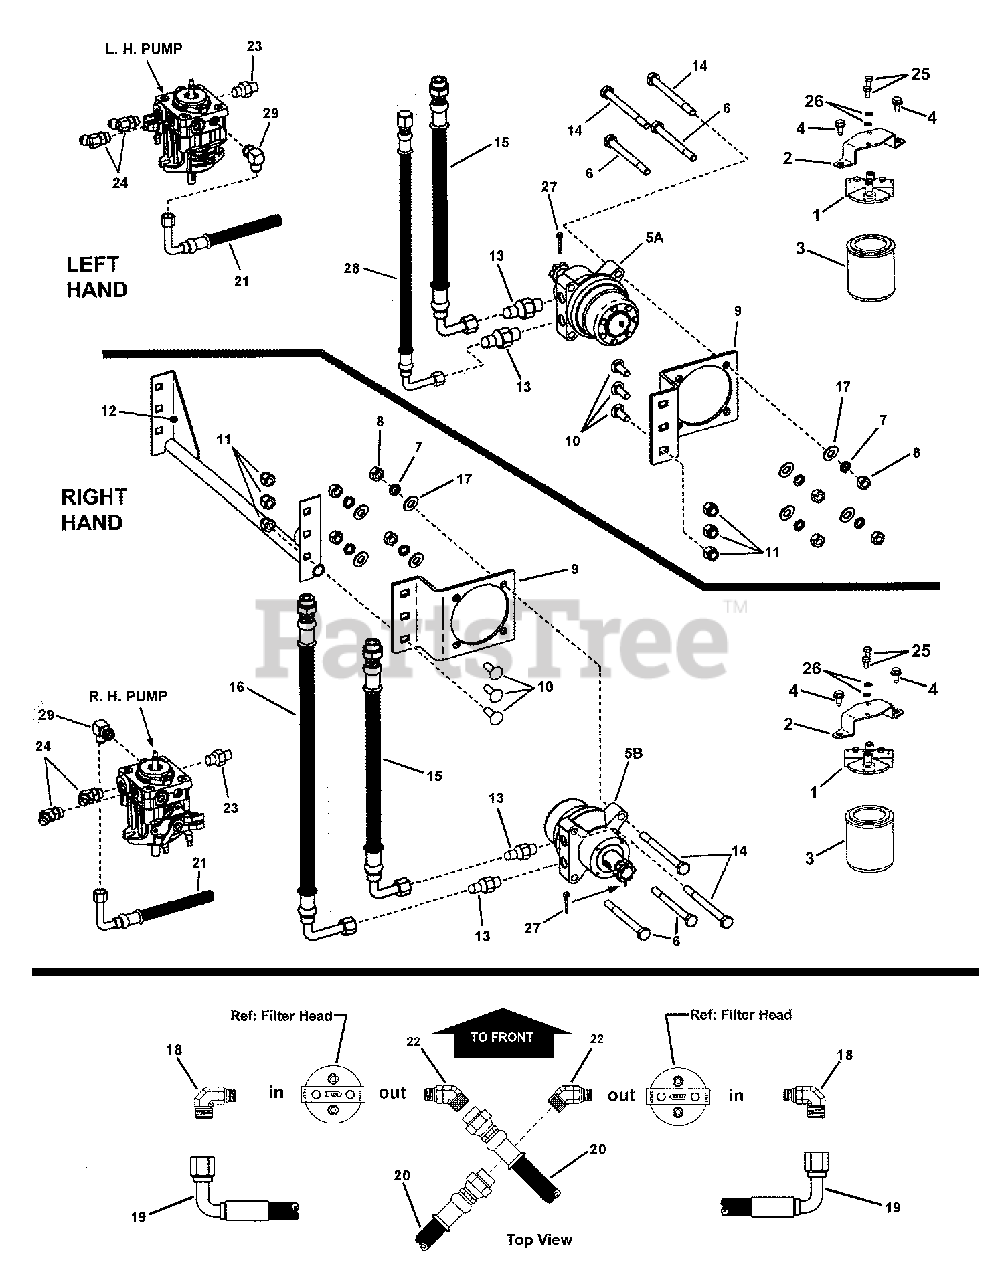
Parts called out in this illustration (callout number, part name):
1	FILTER HEAD
2	BRACKET, Filter
3	FILTER, OIL
4	SCREW, 5/16-18 x 5/8" Hex Washer Self-Tap
5A	MOTOR, Hydraulic, Left Hand
5B	MOTOR, Hydraulic, Right Hand
6	BOLT, 1/2-13 x 6" Hex Head Cap, GR 5
7	WASHER, 1/2" Split Lock
8	NUT, 1/2-13 HEX
9	PLATE, Mounting
10	BOLT, 1/2-13 x 1-1/2" Square Neck Carriage, GR 5
11	NUT, 1/2-13 Hex Nyloc
12	WELDMENT, Rear Crossbrace
13	CONNECTOR, Straight Hydraulic (Parker # 8-10 F5OLO-S)
14	BOLT, 1/2-13 x 3-3/4" Hex Head Cap
15	HOSE, 15-1/2" Hydraulic (Parker # F436JCJ9080808-15.50)
16	HOSE, 17-1/2" Hydraulic (Parker # F436BKJCJ5080808-17.5)
17	WASHER, .531 I.D. Flat
18	CONNECTOR, 90-Degree Hydraulic (Parker # 8-6 C5OLO-S)
19	HOSE, 18-1/2" (Parker # R836BKJCJ9090808-18.5)
20	HOSE, 12-1/4" (Parker # R836BKJ9NR080008-12.5)
21	HOSE, 6-1/2" (Parker # R836BKJ9NR080008-6.5)
22	CONNECTOR, 45-Degree Hydraulic (Parker #8-6 V 50L0-S)
23	CONNECTOR, Straight Hydraulic (Parker # 8-6 F5OLO-S)
24	CONNECTOR, 45-Degree Hydraulic (Parker # V5OLO-S)
25	SCREW, 1/4-20 x 1/2" Hex Head Cap, GR 5
26	WASHER, 1/4" Split Lock
27	PIN, 1/8 x 1-1/2" Cotter
28	HOSE, 19-1/2" (Parker # F436BKJCJ5080808)
29	CONNECTOR, 90-Degree Hydraulic (Parker # 8-10 C5OLO-S)
